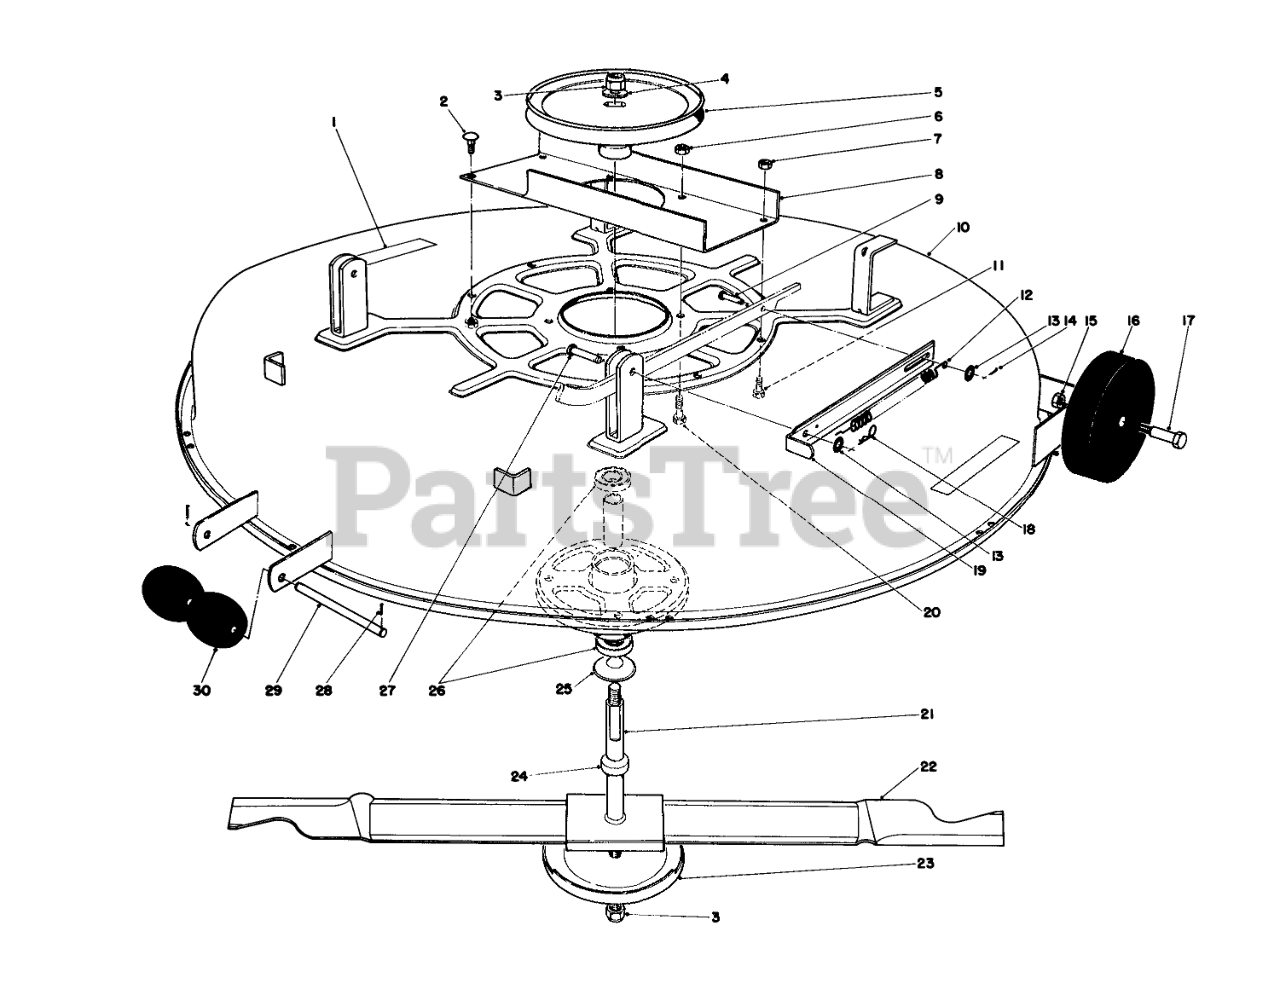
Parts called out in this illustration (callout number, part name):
1	Caution Decal
2	SCREW-CARR
4	Thrust Washer
5	BLADE DRIVE PULLEY
6	NUT-LOCK, CONE
7	NUT-HEX, SIDE DEFORM
8	REINFORCEMENT CHANNEL
9	PIN-CLEVIS
10	Mulcher Deck
11	SCREW-HH
12	DECK TENSION SPRNG O
13	WASHER-FLAT
14	PIN-COTTER
15	Nut
16	DECK WHEEL
18	PIN-COTTER
19	DECK SPRING STRAP R
20	SCREW-HH
21	Spindle Assembly (Incl. Ref. #24-26)
22	Blade
23	Cup
24	SPACER
25	DUST COVER
26	BEARING
27	PIN-CLEVIS
28	PIN-COTTER
29	ROLLER SHAFT
30	ROLLER
